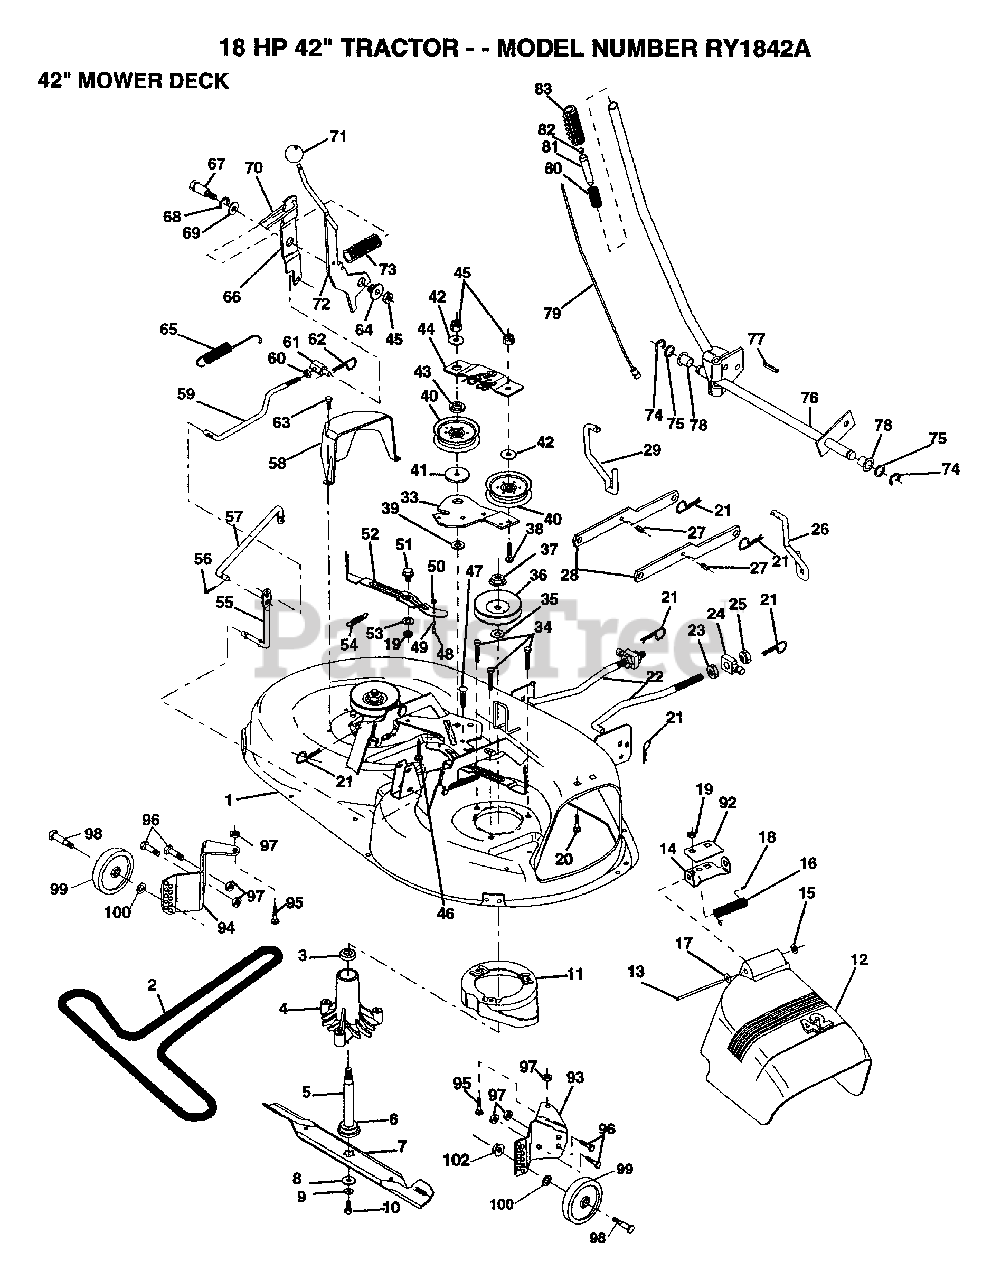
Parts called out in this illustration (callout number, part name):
2	BELT-V.92.4.MWR
3	BEARING
4	HSG ASM MANDREL
6	BEARING.BALL
8	WASHER BLADE
10	BLADE BOLT
12	DEFLECTOR.SHIELD
13	HINGE ROD
14	DEFLECTOR BRKT
15	NUT PUSH M
16	SPRING TORSION
17	WASHER
18	CAP-SLEEVE LT
20	BOLT
22	LINK.FRONT
23	NUT
24	TRUNION
25	NUT.LK.W/WSH.1/2.
26	LIFT LINK RH
27	"PIN,SPRING"
29	LINK LIFT LH
33	IDLER ARM
35	WASHER
38	BOLT
39	HARDENED WASHER
40	FLAT IDLER PULLEY
41	SPACER RETAINER
42	WASHER GT
43	RETAINER SPACER
44	IDLER ARM STIFF
46	BOLT CARRIAGE
47	XMAS TREE FASTNER
48	SHOULDER BOLT
50	LOCKNUT
52	BRAKE PAD ARM ASM
53	HARD SMALL WASHER
54	SPRING EXTENSION
55	PIVOT ROD
57	CLUTCH ROD SECOND
60	NUT
61	TRUNION
62	RETAINER M
63	SCREW LT
64	BUSHING
65	RETURN SPRING
66	CLUTCH ARM SECOND
67	SHOULDER BOLT
68	RING
69	WASHER
70	SPRING KEEPER
75	WASHER
76	LIFT SHAFT ASM
77	PIN-GROOVE LT
78	NYLON BEARING
83	GRIP
92	STIFFENER BRKT
96	BOLT
99	WHEEL.GAGE.BLK.PL
100	WASHER
102	NUT SPECIAL T
